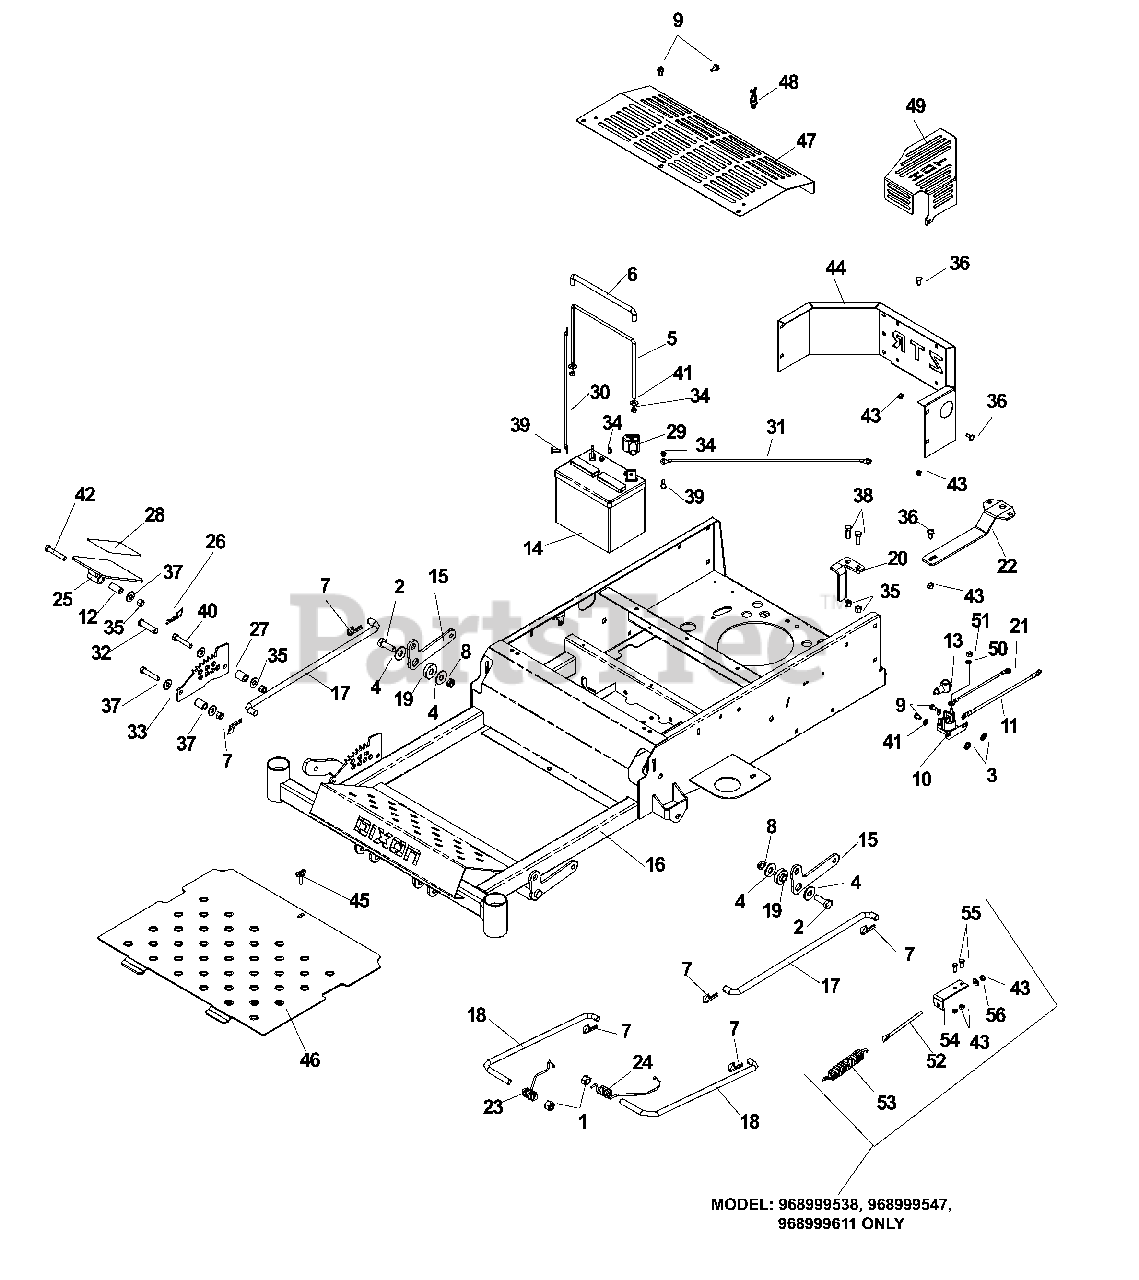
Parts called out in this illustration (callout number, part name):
1	NUT 1/2-13 HEX NYLOC ZD
2	HCS 1/2-13 X 1-1/2 GR 5 ZD
3	WASHER 1/4 EXTLW STAR ZD
4	WASHER 1/2" FLAT
5	BATTERY TIE DOWN
6	TIE DOWN INSULATOR
7	PIN, COTTER 1 3/4
8	NUT, 1/2-13 THIN PROF NYL
9	SCREW 1/4 X 5/8
10	SOLENOID
11	BATTERY GROUND CABLE
12	BUSHING
13	TERMINAL COVER-SM
14	BATTERY, 12 V 330 AMP TBR
15	REAR LIFT LINK
17	LINK DECK LIFT
18	TRAILING ROD
19	IDLER SPACER
20	CLUTCH STOP
21	SOLENOID TO STARTER CABL
23	SPRING TORSION RH
24	SPRING TORSION LH
25	FOOT PEDAL (PLATED)
26	STAINLESS COTTER
28	FOOT PAD
29	TERMINAL COVER
30	NEGATIVE CABLE 20"
31	POSITIVE CABLE 20"
32	CLEVIS PIN 1/2 X 2 LG
33	LIFT QUADRANT (DK BLUE)
34	NUT 1/4-20 NYLOC
35	NUT 3/8-16 NYLOC
36	BOLT 5/16C X 3/4" CARRIAGE
37	WASHER 3/8 FLAT
38	HCS 3/8C X 1
39	HCS 1/4C X 3/4 HCS
40	HCS 3/8C X 2
41	WASHER 1/4 FLAT
42	HCS 3/8C X 2 1/4
43	NUT 5/16 NYLOC
45	1/4-20 X 3/4 WING BOLT
46	FOOT PLATE DK-BLUE
47	FAN GUARD
48	KURLYLOK RICHCO#BHKL7504
50	WASHER 1/4 INT TOOTH
51	NUT 1/4-20 JAM
52	EYE BOLT 5/16 X 6.00
54	SPRING ANCHOR
55	HCS 5/16C X 3/4
56	FLAT WASHER 5/16 SAE
